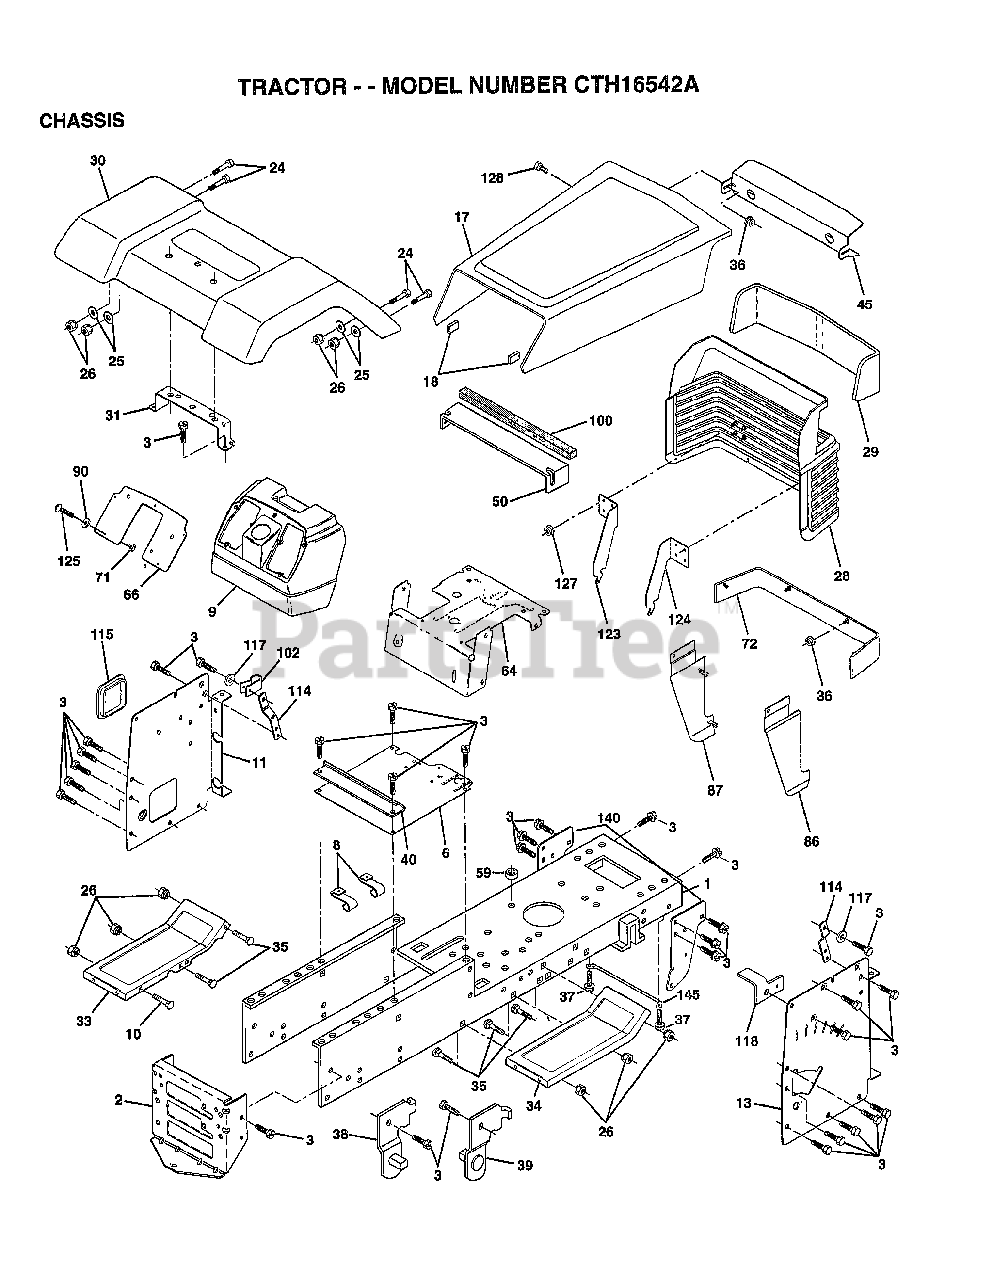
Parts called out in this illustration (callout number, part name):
3	SCREW
6	SADDLE
8	"CLIP,INSULATOR"
9	DASH.PLASTIC.BLK
11	PANEL.DASH.LH.
13	PANEL.DASH.RH.
17	HOOD/GRILLE ASM
24	BOLT
25	WASHER
26	NUT
28	GRILLE ASM WELD
31	BRACKET SUPT FEND
33	FOOTREST.LH.LT/GT
34	FOOTREST.RH.LT/GT
35	BOLT
36	PAL NUT LT
38	BRACKET ASM LH
39	BRACKET ASM RH
40	SPACER FENDER LT
45	BEZEL.LIGHT.SLVR
50	"BAFFLE,HOOD"
64	DASH.LOWER.LT
66	PLATE DASH SILKSC
71	NUT HXKEP 1/4X20
72	STRAP FENDER ASM
86	PANEL SIDE RH ASM
87	PANEL SIDE LH ASM
90	WASHER PM
100	FOAM STRIP T
102	CLIP T
114	BRACKET.SUPT.DASH
115	COVER ACCESS
117	WASHER.SERRATED.
118	BRACKET.CLUTCH.MC
123	BRACKET.PICK.LH.
124	BRACKET.PICK.RH.
125	SCREW
127	PAL NUT
128	SCREW SPECIAL
140	BRKT SUSPENSION
145	"ROD POVOT,CHASSIS"
